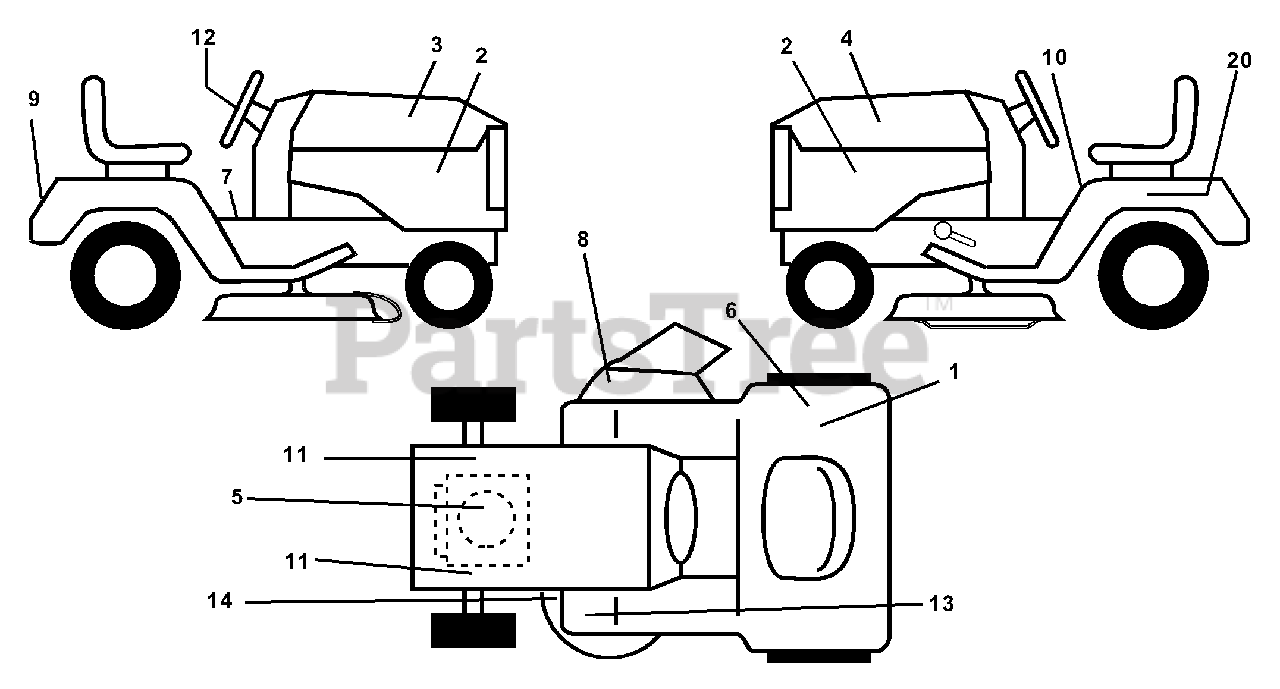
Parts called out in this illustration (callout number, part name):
1	Decal 100 DBA
2	Decal Panel Side B&S Logo
3	Decal Hood RH
4	Decal Hood LH
5	Decal HP Engine
6	Decal Euro Stand CE
7	Decal Saddle Brake
8	Decal Mower Cutfinger Symbol
9	Decal Fender Husq
10	Decal Read Owner's Manual Syms.
11	Decal Chassis Hot Muffler
12	Decal Wheel Steering
13	Decal Brake/Clutch Symbol LT
14	Decal V-Belt Schematic
20	Decal Bat Dan/Psn
